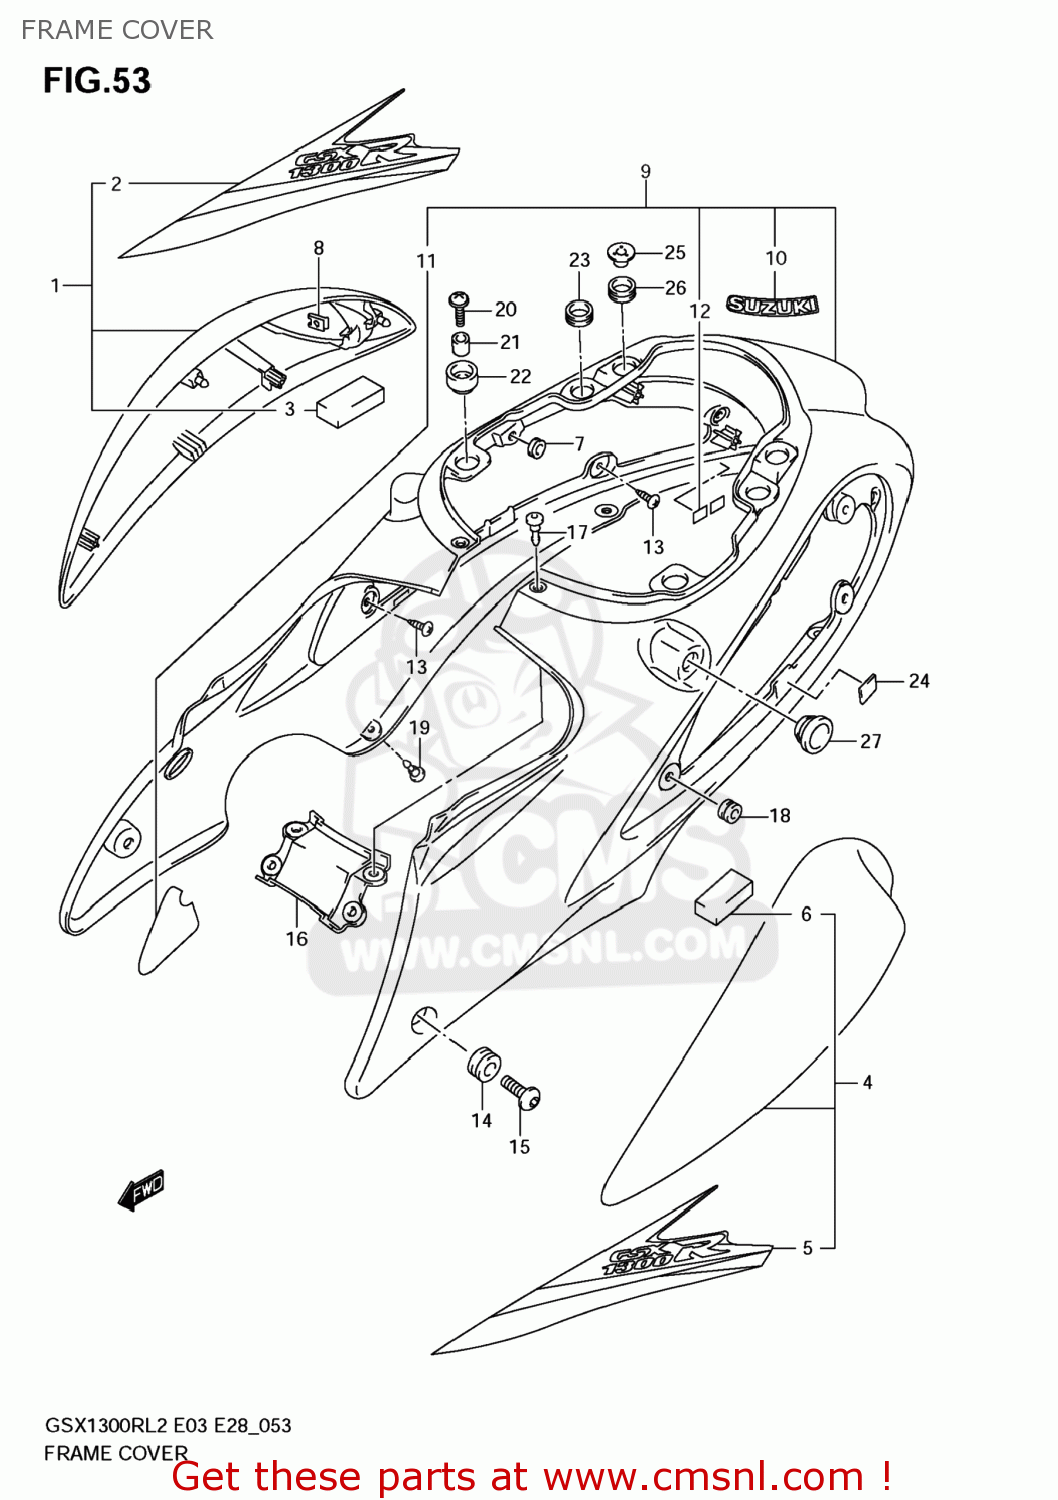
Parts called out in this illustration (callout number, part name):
1	COVER,FRAME,R(B
2	TAPE,FRAME COVER,R
3	CUSHION,FRAME COVER
4	COVER,FRAME,L(
5	TAPE,FRAME COVER,L
6	CUSHION,FRAME COVER
7	CUSHION
8	NUT
9	COVER,FRAME CTR
10	EMBLEM(GRAY)
11	TAPE,CTR
12	CUSHION,SEAT TAIL COVER LWR RR
13	SCREW(5X15)
14	CUSHION
15	SCREW(6X20)
16	LID,FRAME COVER CTR
17	CLIP(BLACK)
18	CUSHION
19	CLIP
20	SCREW(6X20)
21	SPACER(6.5X10X11)
22	CUSHION,SEAT TAIL COVER CTR
23	CUSHION,FRAME COVER UPR RR
24	PROTECTOR(170X95X3.0)
25	WASHER,FRAME COVER
26	CUSHION,FRAME COVER UPR RR RR
27	CUSHION,FRAME COVER CTR
